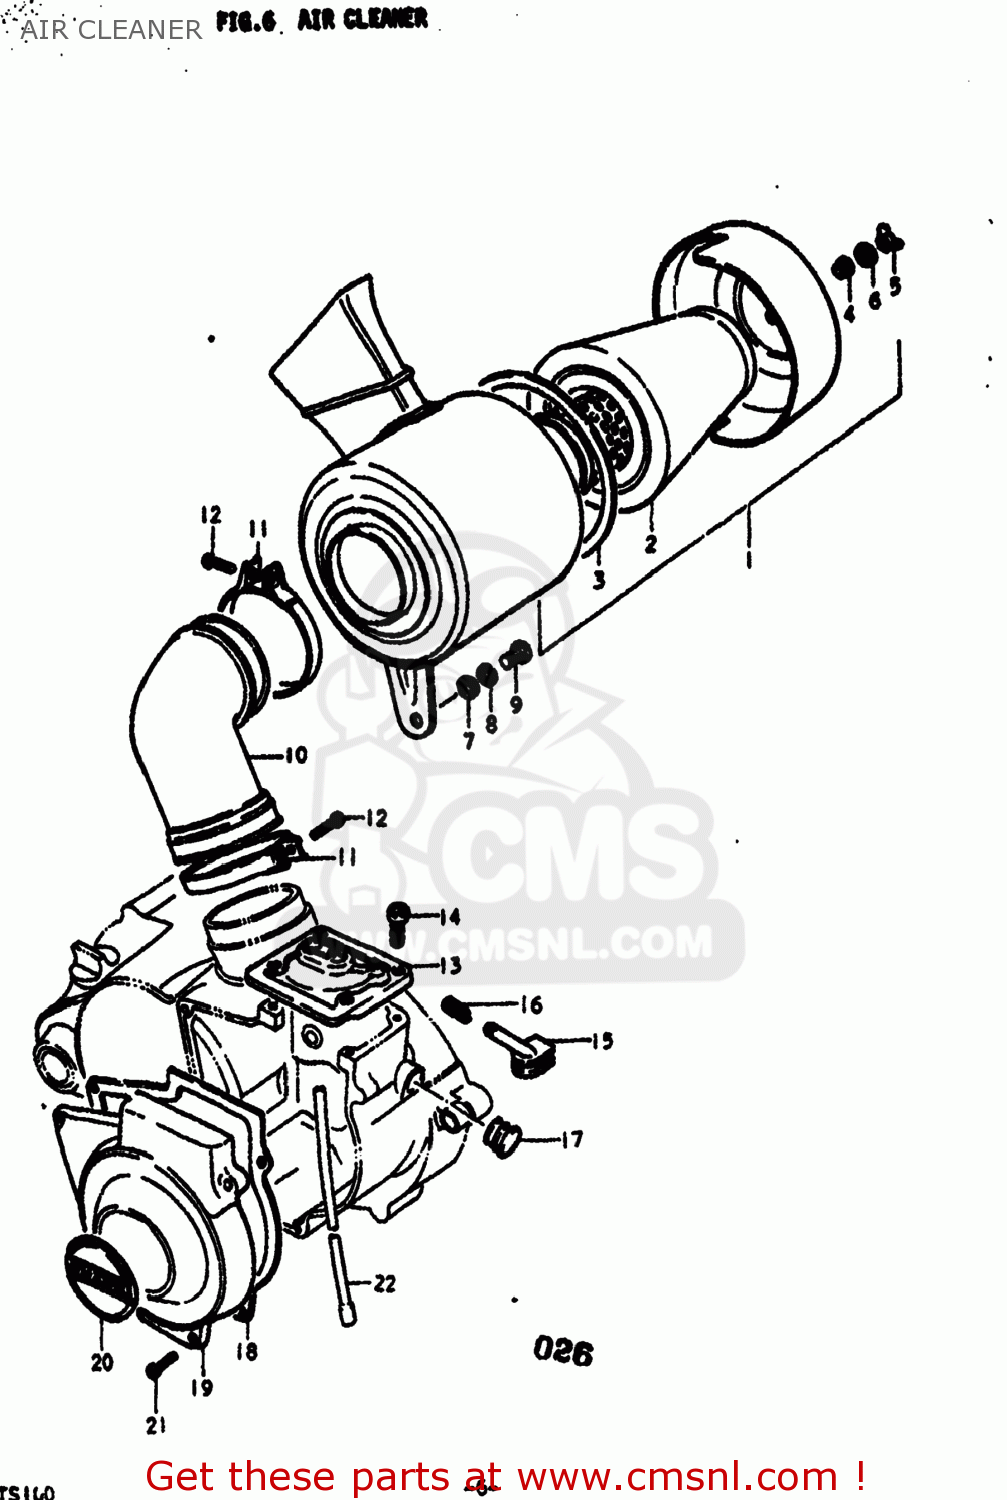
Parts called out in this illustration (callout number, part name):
1	CLEANER ASSEMBLY,AIR
2	FILTER ASSY,AIR CLEANER
4	GASKET
5	NUT
6	HOLDER,FILTER
7	WASHER
8	LOCK WASHER
9	SCREW
10	TUBE,AIR CLEANER OUTLET
11	CLAMP
12	SCREW
13	COVER,CARBURETOR,TOP
14	SCREW
15	GROMMET
16	SPRING
17	Plug
18	GASKET,CARB INSPECTION CAP (NAS)
19	CAP,CARBURETOR INSPECTION
20	EMBLEM,CARB INSPECTION CAP
21	SCREW
22	HOSE
